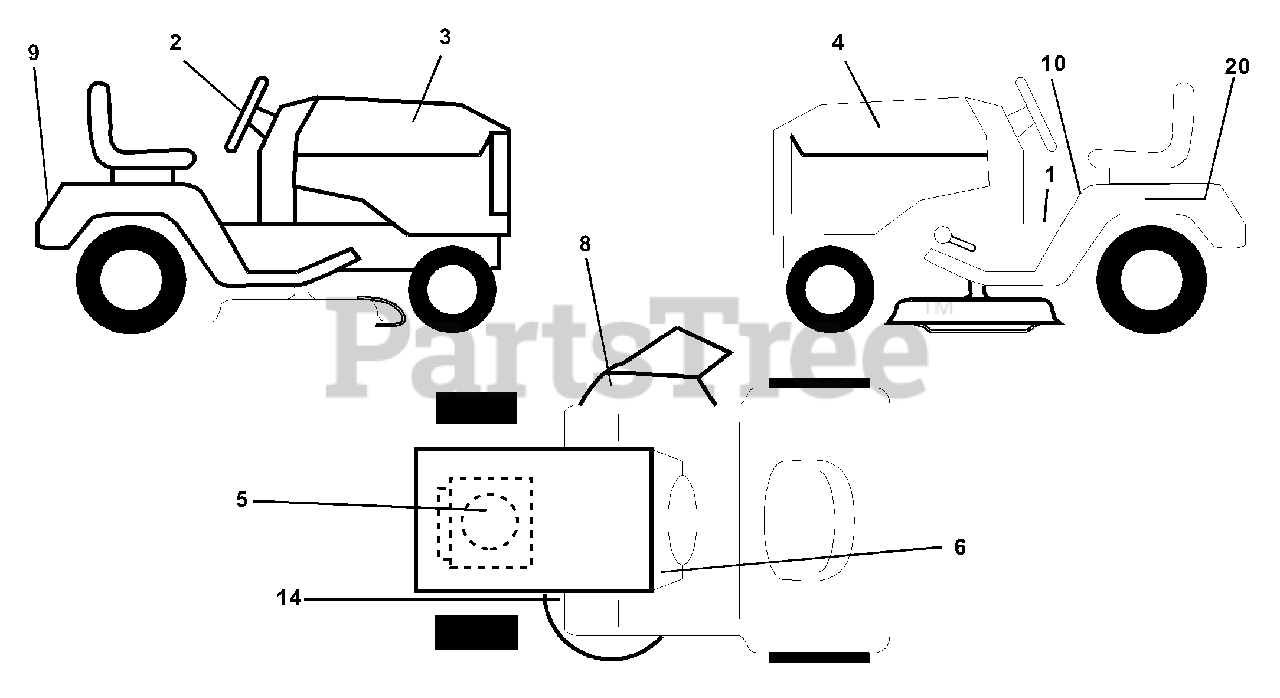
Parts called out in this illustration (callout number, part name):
1	Decal Oper Step Thru Eng/Fr
2	Decal Wheel Steering
3	Decal Hood RH
4	Decal Hood LH
5	Decal HP Engine
6	Decal Dash Logo
8	Decal Warning
9	Decal Fender Husq
10	Decal Fender Danger Eng/Fr
14	Decal V-Belt Schematic
20	Decal Bat Dan/Psn
